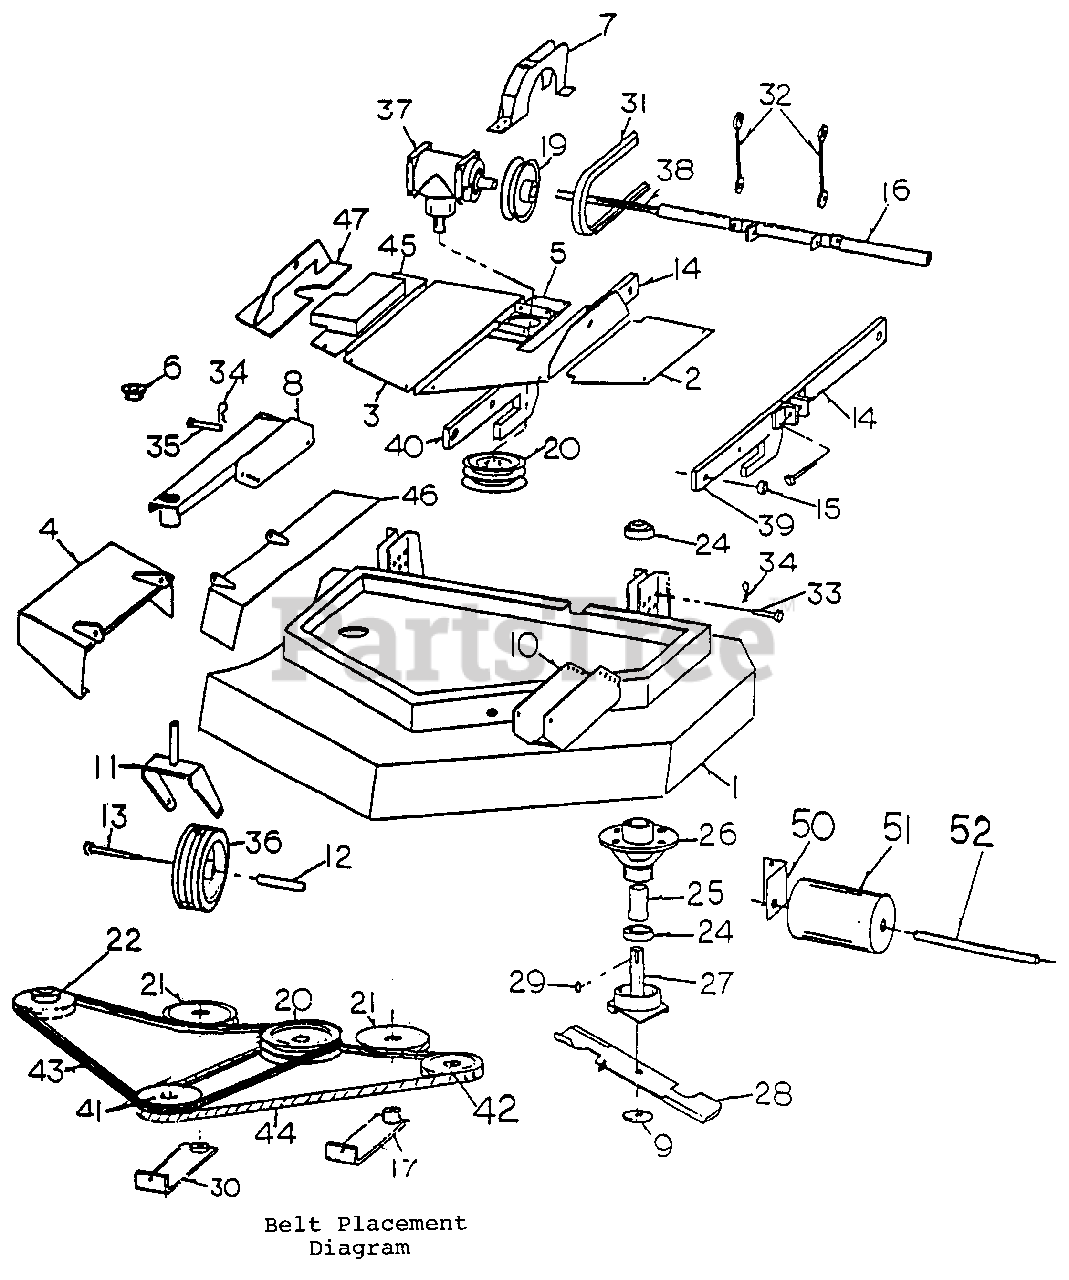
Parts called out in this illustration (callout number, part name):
1	MOWER DECK
2	COVER (Small)
3	COVER (Large)
4	FOOT GUARD
5	GEAR BOX MOUNT
6	GAGE WHEEL BUSHING
7	BELT GUARD
8	GAGE WHEEL MOUNT
9	SPRING WASHER
10	BRACKET, GAGE WHEEL MOUNT
11	FORK, GAGE WHEEL
12	AXLE, GAGE WHEEL
13	GAGE WHEEL BOLT
14	DECK LIFT ARM BACK ADJUSTABLE
15	BUSHING, DECK LIFT ARM
16	CROSSBAR
17	BELT TIGHTENER
17	SPACER, IDLER
19	PULLEY, GEAR BOX(Input)
20	PULLEY, GEAR BOX(Output)
21	PULLEY, IDLR
22	PULLEY, SPINDLE
22	WASHER SPINDLE
24	BEARING SPINDLE
25	SPACER SPINDLE
26	HOUSING SPINDLE
27	SHAFT SPINDLE
29	KEY SPINDLE
30	BELT TIGHTENER
31	BELT, DRIVE
32	CABLE, DECK
33	PINS, DECK
34	HAIR PIN
35	PINS, GAGE WHEEL
36	GAGE WHEEL
37	GEAR BOX
38	CROSS BAR PIN
39	L.H 1 DECK LIFT ARM FRONT ADJUSTABLEW L.H.
40	R.H. 1 DECK LIFT ARM FRONT ADJUSTABLE R.H.
41	PULLEY, DOUBLE A
42	PULLEY, LEFT SIDE SPINDLE
43	BELT, DECK LONG
44	BELT, DECK SHORT
45	SMALL COVER
46	FOOT GUARD MOUNT
47	DECK MOUNT
50	ROLLAR BRACKET
51	RUBBER ROLLAR
52	SHAFT, ROLLAR
